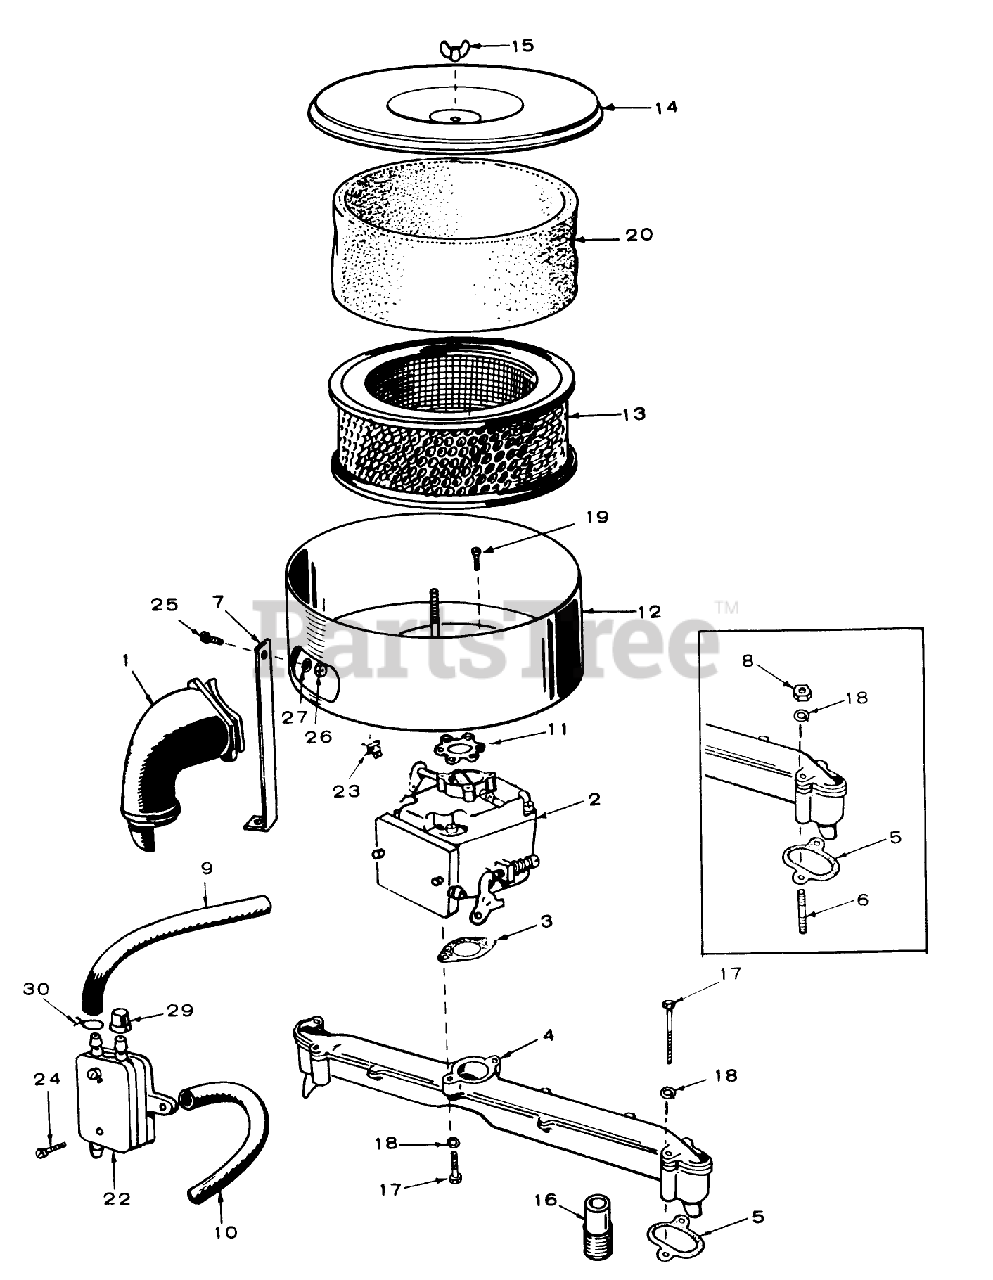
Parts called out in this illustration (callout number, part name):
3	Carburetor Mounting Gasket
6	Stud-Intake Manifold
8	Nut-Intake Manifold
9	Hose-Fuel Pump To Carburetor
10	Hose-Fuel Pump Vacuum
13	ELEMENT-AIR CLEANER
15	Wing Nut-Air Cleaner Cover
16	Nipple, (1" x 2 1/2")-Exhaust
17	SCREW, HEX CAP
17	Hex Bolt-Intake Manifold Mounting
18	WASHER, LOCK
18	Carburetor Mounting (1/4")
18	Intake Manifold Mounting (5/16")
19	SCREW-RD HD10-32X3/8
22	Fuel Pump
25	Hex Bolt 1/4-20 X 1/2
26	Hex Nut 1/4-20
27	Lockwasher
30	Clamp, Hose (7/16")
